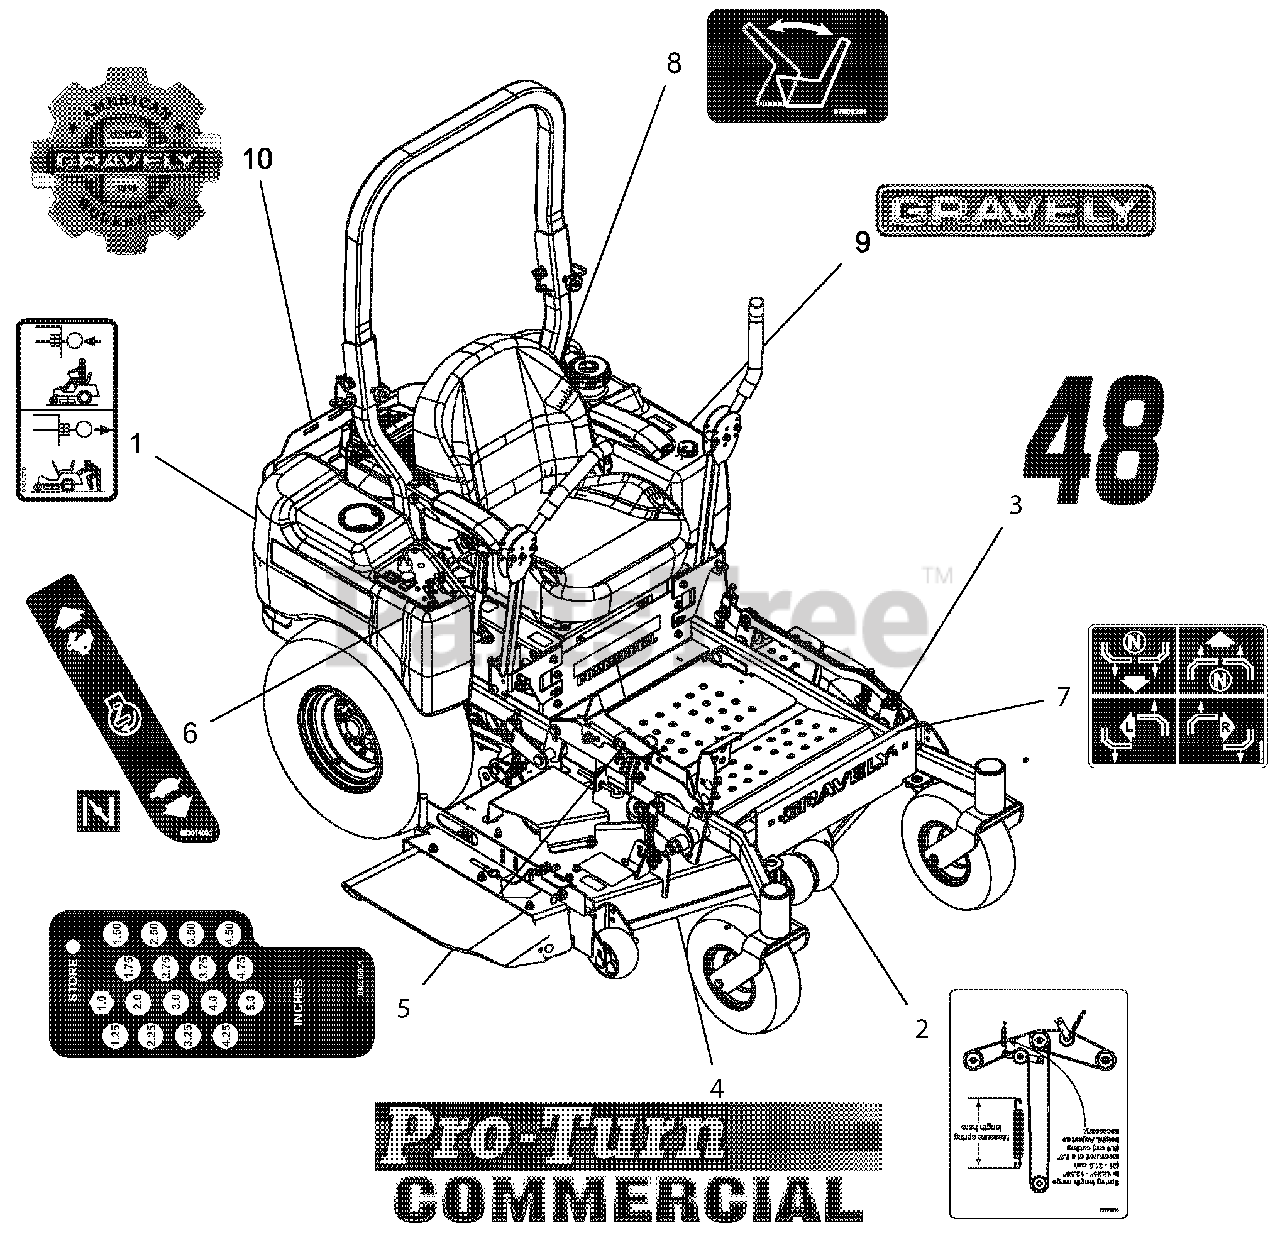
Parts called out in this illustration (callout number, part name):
1	DECAL, TRANSMISSION DISCONNECT
2	DECAL, BELT ROUTING
3	DECAL, 48"
4	DECAL, 48" PRO-TURN
5	DECAL, HEIGHT OF CUT
6	DECAL, SPEED CONTROL
7	DECAL, INSTRUCTIONAL - STEERING
8	DECAL, SEAT RELEASE
9	DECAL, FUEL TANK-GRAVELY
10	DECAL, GRAVELY HERITAGE-LARGE
